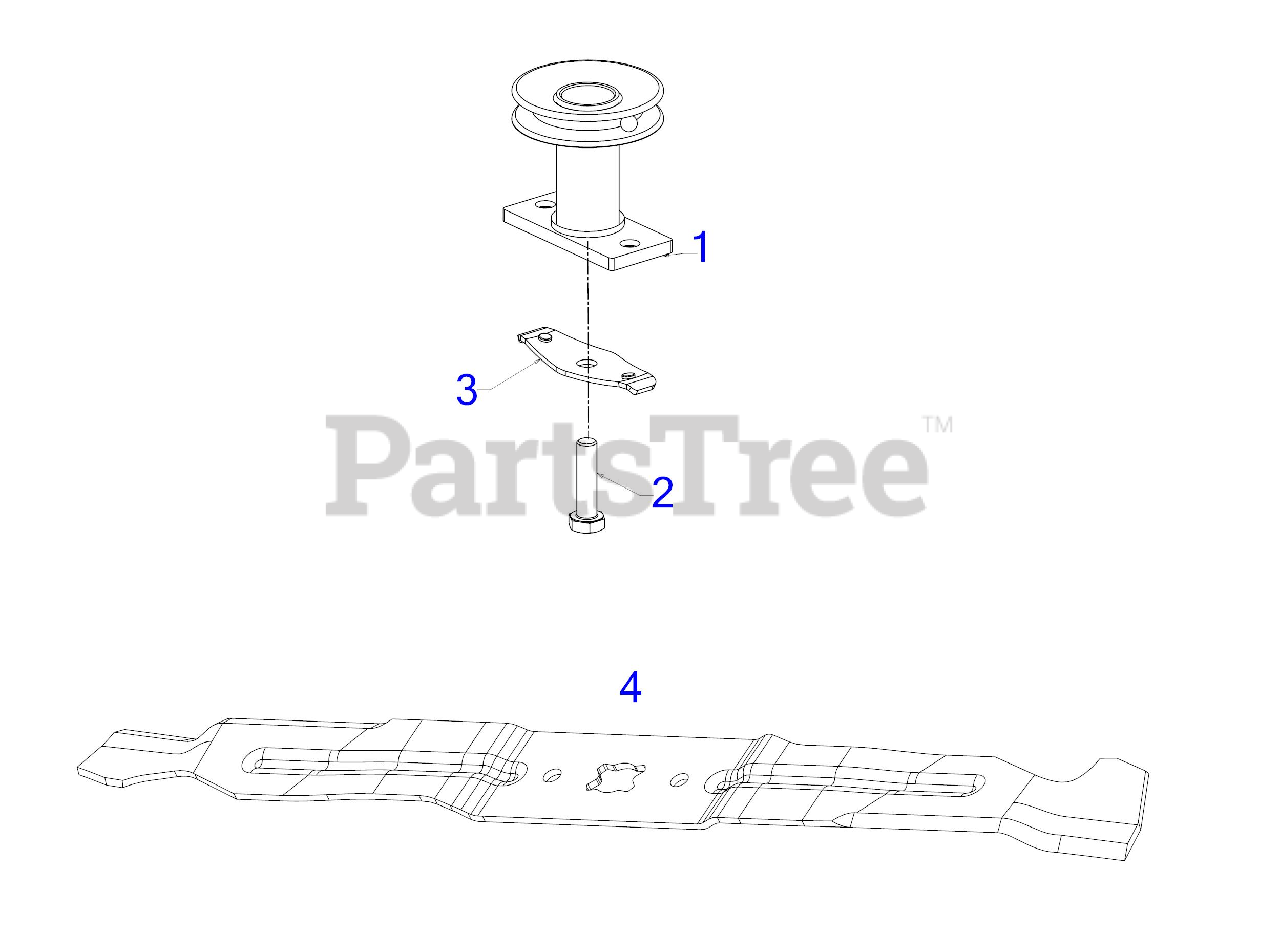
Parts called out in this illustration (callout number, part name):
1	DRIVE PULLEY
2	SCREW 3/8-24 x 1.50 GR8
3	BLADE BELL SUPPORT
4	21" MULCHING BLADE
